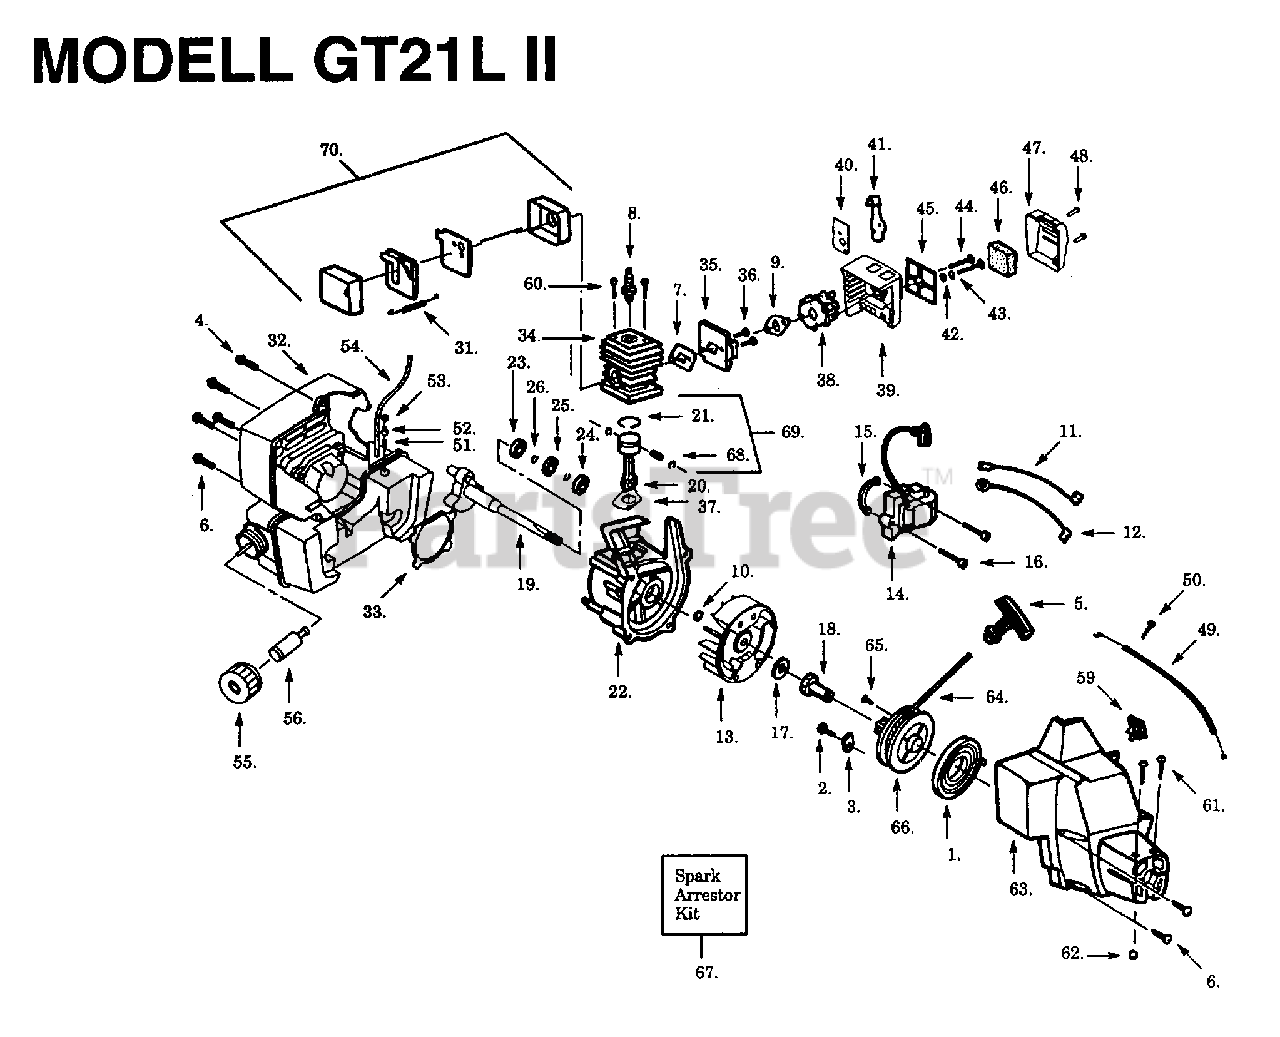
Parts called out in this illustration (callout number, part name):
1	SPRING-STARTER
2	SCREW 8-16 X 9/16 (PLAS
5	HANDLE-STARTER
6	SCREW - SHROUD
7	GASKET
8	SPARK PLUG CJ8 NLA
9	GASKET
10	RETAINING RING
11	LEAD WIRE
12	GROUND WIRE
13	FLYWHEEL
14	IGNITION MODULE
15	SPACER - IGNITION MODULE
17	WASHER FLAT
18	COUPLING-DRIVE
19	CRANKSHAFT ASSEMBLY
20	CONNECTING ROD
21	PISTON RING
22	CRANKCASE ASSY
23	BEARING
25	SEALING RING
31	MUFFLER SPRING
32	TANK
33	GASKET, CRANKCASE
36	SCREW - CARB. ADAPTOR
37	REPL BY 530 01 92-23
38	CARBURETOR
40	CHOKE PLATE
41	CHOKE FLAP
43	CHOKE SPACER
45	FILTER PLATE
46	AIR FILTER FOAM
47	AIR FILTER COVER
48	SCREW - THROTTLE HOUSING
49	THROTTLE CABLE
51	VALVE-CHECK (DUCKBILL)
55	REPL BY 530 01 43-47
56	FUEL PICK UP ASSY
59	REPL BY 530 06 95-72
61	SCREW-10-24 X 1-3/8 (UN
62	LOCKNUT-HEX 10-24
63	REPL BY 530 04 74-91
65	SCREW-6-19X9/32 PAN/SEM
66	STARTER PULLEY KIT
67	KIT-SPARK ARRESTOR (OLD STYLE)
68	WRIST PIN RET.
69	PISTON
70	MUFFLER KIT
